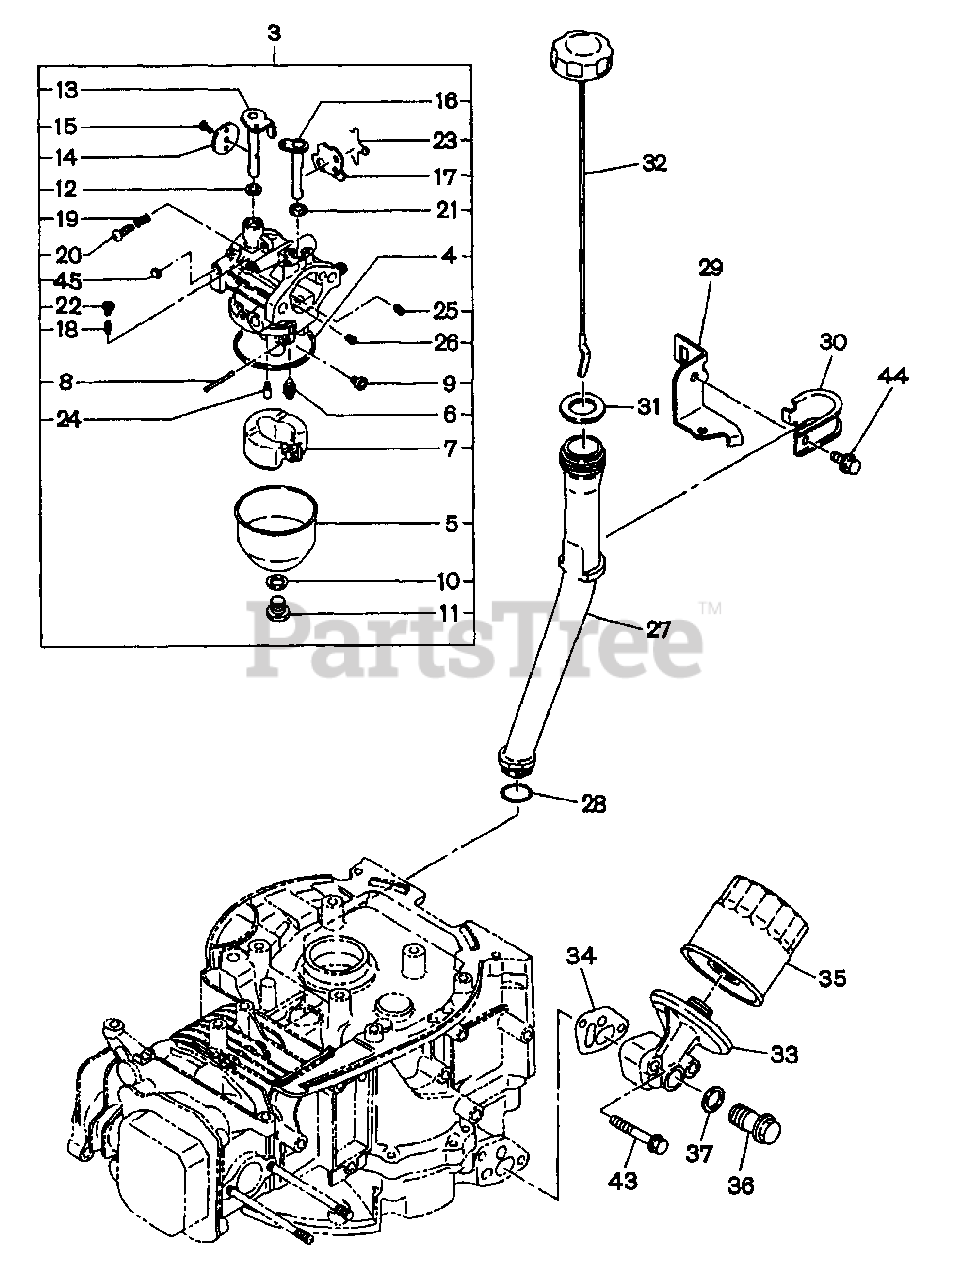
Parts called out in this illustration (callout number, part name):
3	CARBURETOR ASS'Y
4	GASKET, float chamber
5	CHAMBER, float
6	VALVE, float
10	GASKET, chamber set
11	PLUG, chamber set
13	THROTTLE SHAFT ASS'Y
14	THROTTLE VALVE
16	CHOKE SHAFT ASS'Y
17	CHOKE VALVE
18	SLOW JET (#42)
20	ADJUST SCREW
22	PLUG, slow jet
24	PLUG, slow passage
25	JET, slow air bleed
26	JET, main air bleed
28	O-RING
29	BRACKET, oil filler
30	CLAMP, oil filler
32	OIL GAUGE, compl.
33	OIL FILTER BRACKET
34	GASKET, oil filter bracket
35	OIL FILTER ASS'Y
36	OIL DRAIN PLUG
43	FLANGE BOLT
44	FLANGE BOLT
45	PLUG, expansion
